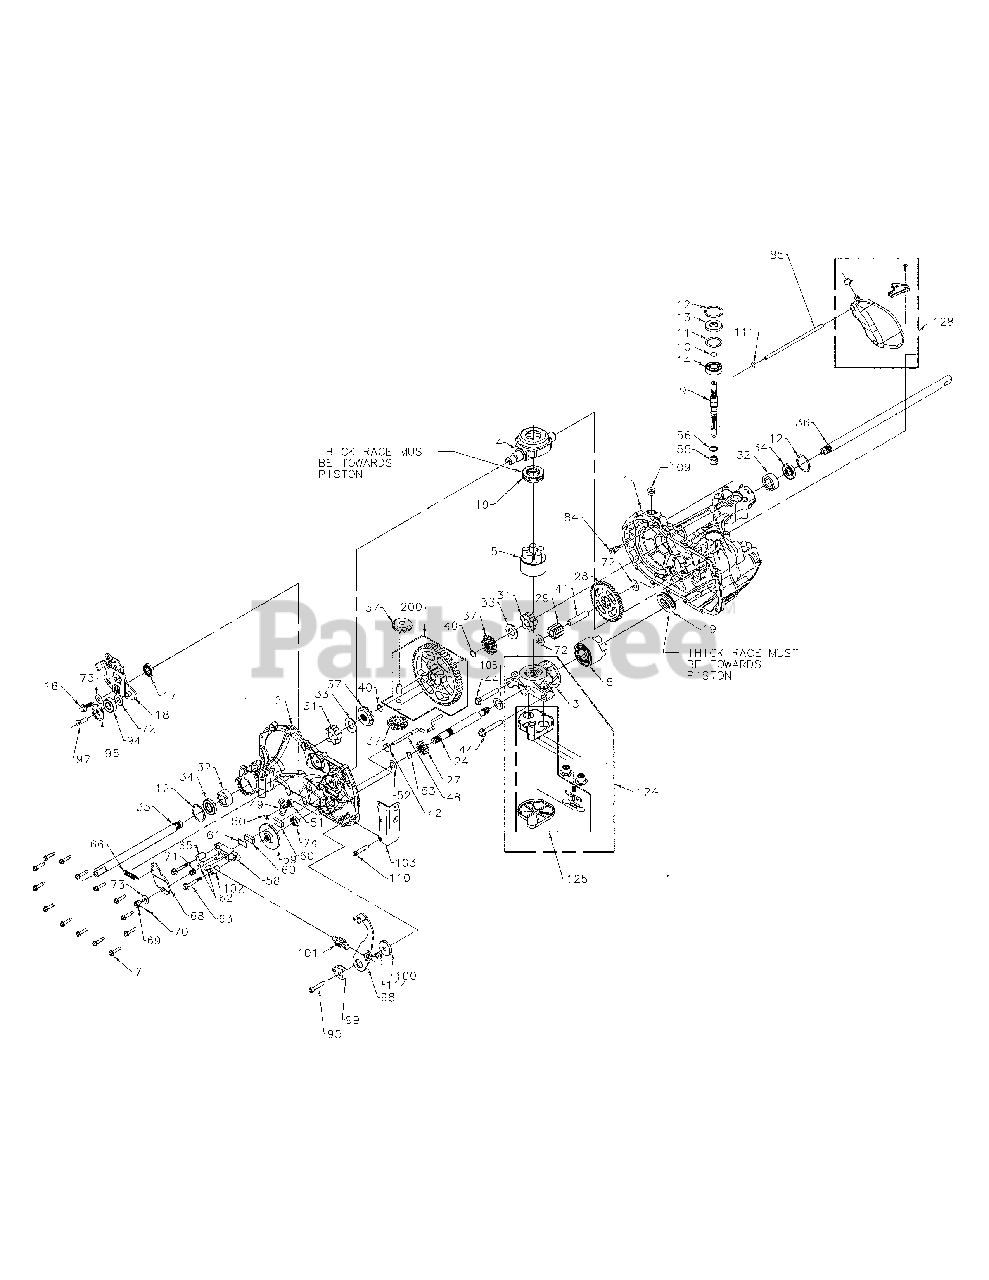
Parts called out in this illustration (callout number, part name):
1	Assembly. Main Housing
1	Housing. Main
1	Bushing .865 X . 985 X . 790
1	Pin. Standard Headless
2	Assembly. Side Housing
2	Housing. Side
2	Bushing .865 X .985 X .790
2	Bushing. .624 X .719 X .562
3	Assembly. Center Section
3	Center Section 5-Piston
3	Bushing. . 707 X . 788 X .591
4	Trunnion. Swashplate
5	Assembly. Block
5	Block. Cylinder
5	Piston
5	Spring. Compression
5	Washer. Thrust
7	Screw. Hex Washer 1/4-20 X 1.125
9	Shaft. Input
10	Ring. Retaining
11	Washer. Flat 1.23 X 1 .57 X .04
12	Ring. Retaining
13	Seal. Lip17X40 X 7
14	Bearing. Ball 17 X 40 X 12
16	Bolt. Hex Flange 5/1 6 24 X . 94 W/ Patch
17	Seal. Lip 18 X 32 X 7
18	Arm. Control
19	Bearing. Thrust 30 X 52 X 13
24	Shaft. Motor
27	Gear. 13T Pinion
28	Gear. 10t/48T
29	Gear. 10T Jackshaft
31	Bushing. Sleeve Inboard
32	Bushing. Sleeve .75 X 1 . 575 X .625
33	Washer. Flat .77X1.5X .1 0
34	Seal. Lip . 75 X 1 . 5 77 X . 250
35	Shaft. Axle .75 X 11 .39 DD. R. H.
36	Shaft. Axle .75 X 17-99 DD. L. H.
37	Kit. Miter Gear
37	Gear. Miter 12T Splined
37	Gear. Miter 12T .50 Id
37	Bulletin. Miter Gear
40	Ring. Spiral Retaining
41	Pin. Jackshaft .50 X 2 43
42	Magnet. Ring
44	Bolt. Hex Flange 3/8-24 X 2.5
48	Rod. Actuator Bypass
49	Arm. Bypass
50	Ring. Retaining .250 External
51	Seal. Lip . 250 X . 750 X . 250 Tc
52	Washer. Flat .63 X 1 .00 X .05
53	Ring. Retaining
55	Spring. Block
56	Washer. Thrust .59 X .79 X .04
58	Kit. Brake Yoke
58	Yoke. Brake
58	Bolt. Sq. Hd. 5/16-24 Ribbed
59	Disk. Brake
60	Puck. Brake
61	Plate. Puck
62	Pin. Brake Actuating
63	Bolt. Hex Hd 1/4 20 X 2 W/Patch
65	Spacer. .26 X .57 X .87
66	Kit. Spring
68	Arm. Brake
69	Nut. Castle 5/16-24
70	Pin. Cotter 3/32 X 3/4
71	Spring. Compression Brake Ant I-Drag
72	Washer. Flat .51 X 1 . 0 X .03
73	Washer. Flat .34 X .88 X .06
74	Kit. Seal
74	Seal. Lip . 625 X 1 . 0 X 25
74	Ring. Ret -Star Washer
74	Bulletin. Shaft Seal
84	Fitting. 5/16 Sae 5/32 Tube
85	Hose. 7. 56 In Expansion Tank
94	Bearing. Ball .62 X 1 . 38 X .44
95	Screw. Socket Hd Cap 5/16-24 X 1 . 5
96	Spacer. Locating
97	Screw. Countersunk 5/16-18 X 1 .0
98	Arm. Return
99	Puck. Adjusting
100	Washer. Flat .32 X 1. 60 X .24
101	Spring. Extension Double Loop
102	Spacer .26 X .56 X .87
103	Bracket. Torque
108	Washer. Flat .71 X 1. 16 X .04
109	Plug. 9/16-18 Metal
110	Screw. Torx Hd 5/1 6 18 X 1 . 5
111	0-Ring. .299 X .505 X .103
114	Spring Gu I De
124	Assembly. Center Section. Filter. Bypass
124	Center Section 5-Piston
124	Base. Filter With Poppet
124	Check Plug Assembly. .027 Bleed. Washer
124	Spring. Bypass .50 In
124	Actuator. Bypass
124	Deflector
124	Bottom. Filter
124	Bushing. . 707 X .788 X .591
125	Assembly. Filter
125	Bottom. Filter
125	Spring. Bypass .50 In
125	Actuator. Bypass
125	Deflector
125	Base. Filter W/ Poppet
127	Kit. Seal & 0 Ring
127	Seal. Lip 17 X 40 X 7
127	Seal. Lip 18 X 32 X 7
127	Seal. Lip . 75 X 1 .577 X .250
127	Seal. Lip .250 X .750 X .250 Tc
127	Seal. Lip .625 X 1 .0 X .25
127	O-Ring .299 X . 505 X .1 03
128	Kit Expansion Tank
128	Tank. Expansion Assembly
128	Bolt. Self Tapping 10-32 X .5
128	Bracket Expansion Tank
200	Kit,60T Bull Gear Diff Pins
200	Gear. 60T
200	Pin. 0. 5 Od
200	Bulletin. Bull Gear
